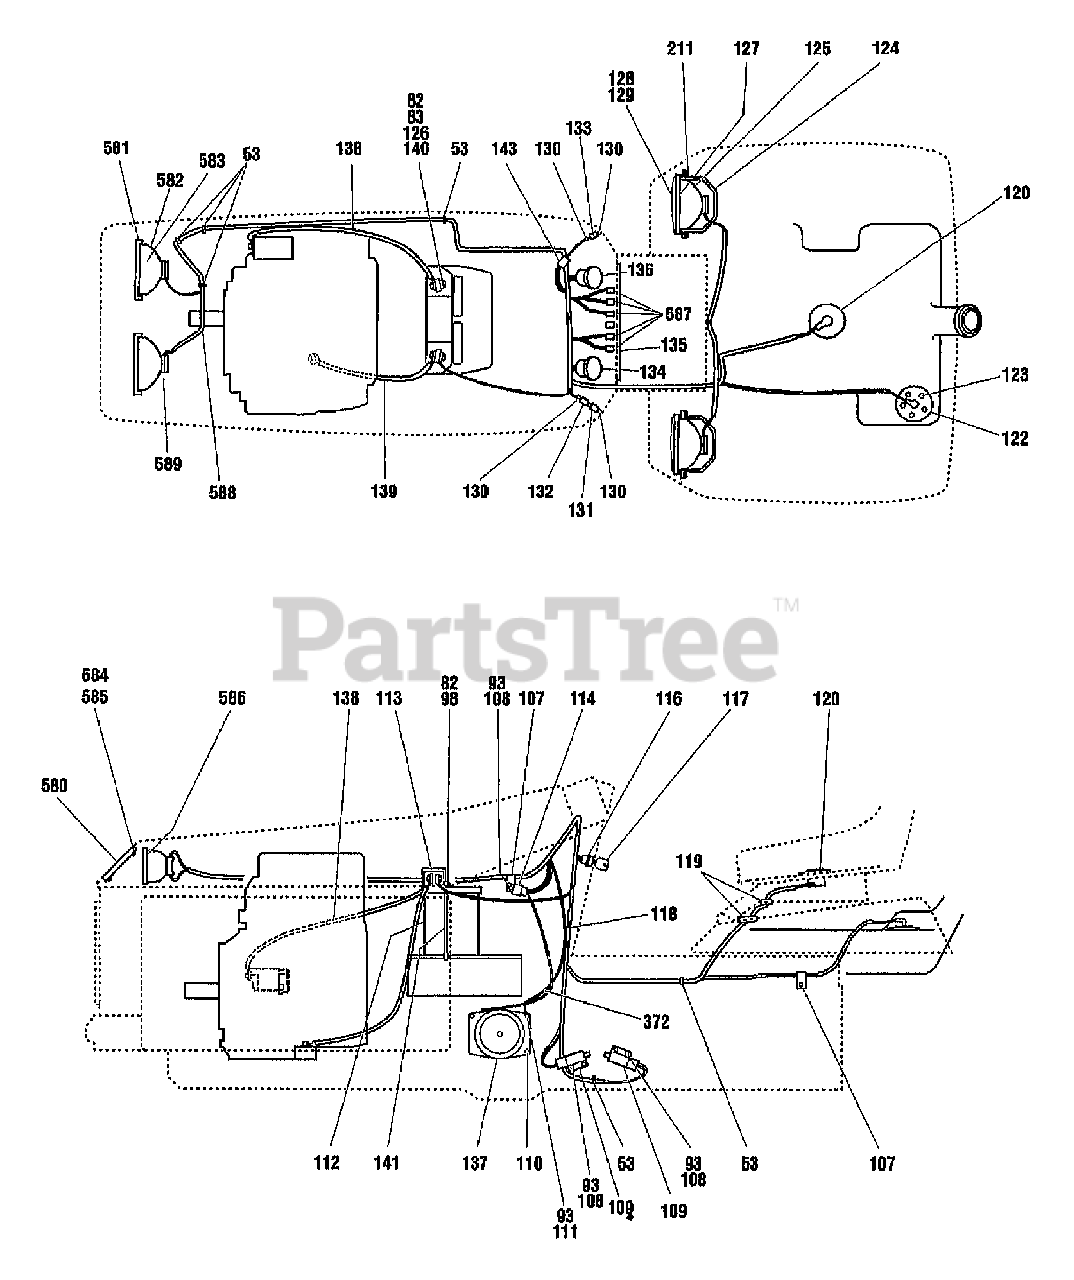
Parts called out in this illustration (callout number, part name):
53	CABLE TIE
82	WASHER-FLAT 1/4 SAE
83	WASHER-LK .25 ZP
93	NUT W/LKWASHER 10-24 ZP
98	NUT-HT LK 1/4-20
107	CLIP-J
108	SCR-TRUSS #10-24 X 5/8
109	SWITCH
111	SCR-SEMS MACH
112	BATTERY
113	BATTERY-HOLDDOWN
114	RELAY-SPEED CONTROL
116	SWITCH-IGNITION
117	KEY-IGNITION
118	HARNESS-MAIN
119	GROMMET {13074,13076}
120	SWITCH-SEAT {13074,13076}
120	SWITCH {13074/076}
122	SENDER-FUEL
124	SHIELD-STONE
125	ASSM-LIGHT
126	NUT-HEX 1/4-20 ZP
127	GASKET
128	LENSE-LH
129	LENSE-RH
130	SCR-FHP #6-32X.50 ZP
131	SWITCH-SPEED CONTROL
132	SWITCH-LIGHT {13074/076}
133	SWITCH-PTO
134	METER-HOUR
135	LENSE
136	GAUGE-FUEL
137	CLUTCH
138	CABLE-BATTERY POSITIVE
139	CABLE-BATTERY NEGATIVE
140	SCR-HH 1/4-20X.75 G5 ZP
141	BOLT-HOOK
143	SENSOR-VOLTAGE
211	NUT-HF/LK 1/4-20 ZP
372	ASSM-LEAD
580	LENSE
581	RETAINER
582	ASSM-LIGHT
583	LIGHTBULB
584	SCR-EXHAUST DEFLECTOR
585	WASHER-.44X.189X.05
586	GASKET
587	BULB (MFG NO. GE 73)
588	HARNESS-HEADLIGHT
589	SOCKET
